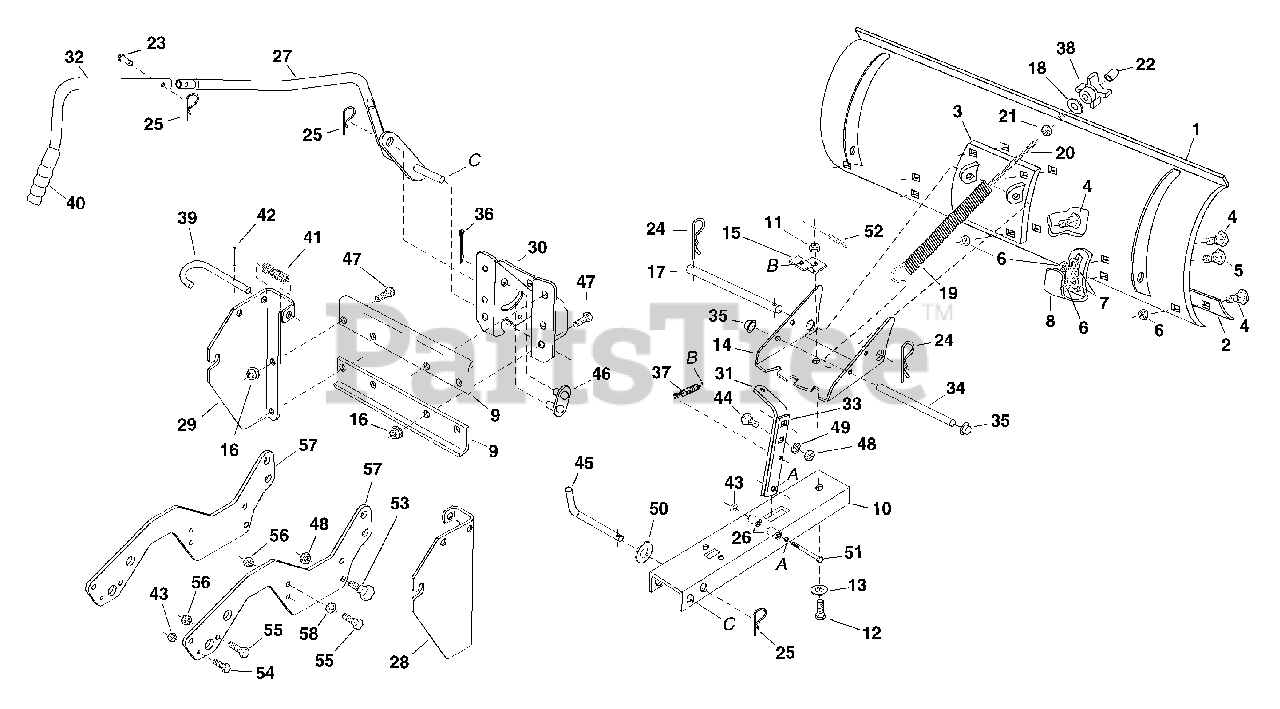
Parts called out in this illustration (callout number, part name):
1	Blade- 46"
2	Wear Plate - 46"
3	Reinforcement Plate Assembly
4	Bolt, Carriage 5/16-18 x 3/4
6	Hex Lock Nut 5/16-18 Thread
7	Washer, 5/16"
8	Skid Shoe
9	Bracket, Angle Support
10	Push Channel
11	Hex Lock Nut6, 1/2=13 Thread
12	Bolt, Special Pivot
14	Plate, Pivot 7 Ga
15	Bracket, Spring Mt.
16	Flanged Lock Nut, 3/8-16 Thread
17	Shaft, Pivot
18	Washer, 3/8" STD
19	Spring, Blade Adjust
20	Hex Bolt, 3/8-16 x 3 -1/2"
21	Hex Nut, 3/8-16 Thread
22	Plastic Cap
23	Pin, Clevis 1/4" x 1-1/2"
24	Pin Hair Cotter #4 (1/8")
25	Pin Hair Cotter #3 (3/32")
26	Spacer, .28 ID x 1"
27	Lift Handle Assembly, Lower
28	Hitch Bracket, RH
29	Hitch Bracket, LH
31	Angle Lock Bar (Long)
32	Lift Handle Upper
33	Angle Lock Bar (Short)
34	Spring Mount Rod
35	Palnut 3/8
36	Cotter Pin 1/8" x 1
37	Angle Lock Spring
39	Pin, Attachment
40	Handle, Grip
41	Spring, Compression
42	Pin, Spring 3/16" x 1
43	Hex Lock Nut 1/4-20 Thread
45	Channel Pivot Pin
46	Lift Link Assembly
47	Hex Bolt, 3/8-16 x 3 -1"
48	Hex Lock Nut, 3/8"-16 Thread
49	Lock Washer 3/8"
51	Hex Bolt, 1/4-20 x 3 1/4" LG. GR 5
52	1/4" x 1" Spring Pin
53	Shoulder Bolt 3/8-16 x 1/2"
56	Hex Nut, 5/16-18 Nylock
57	Frame Bracket
